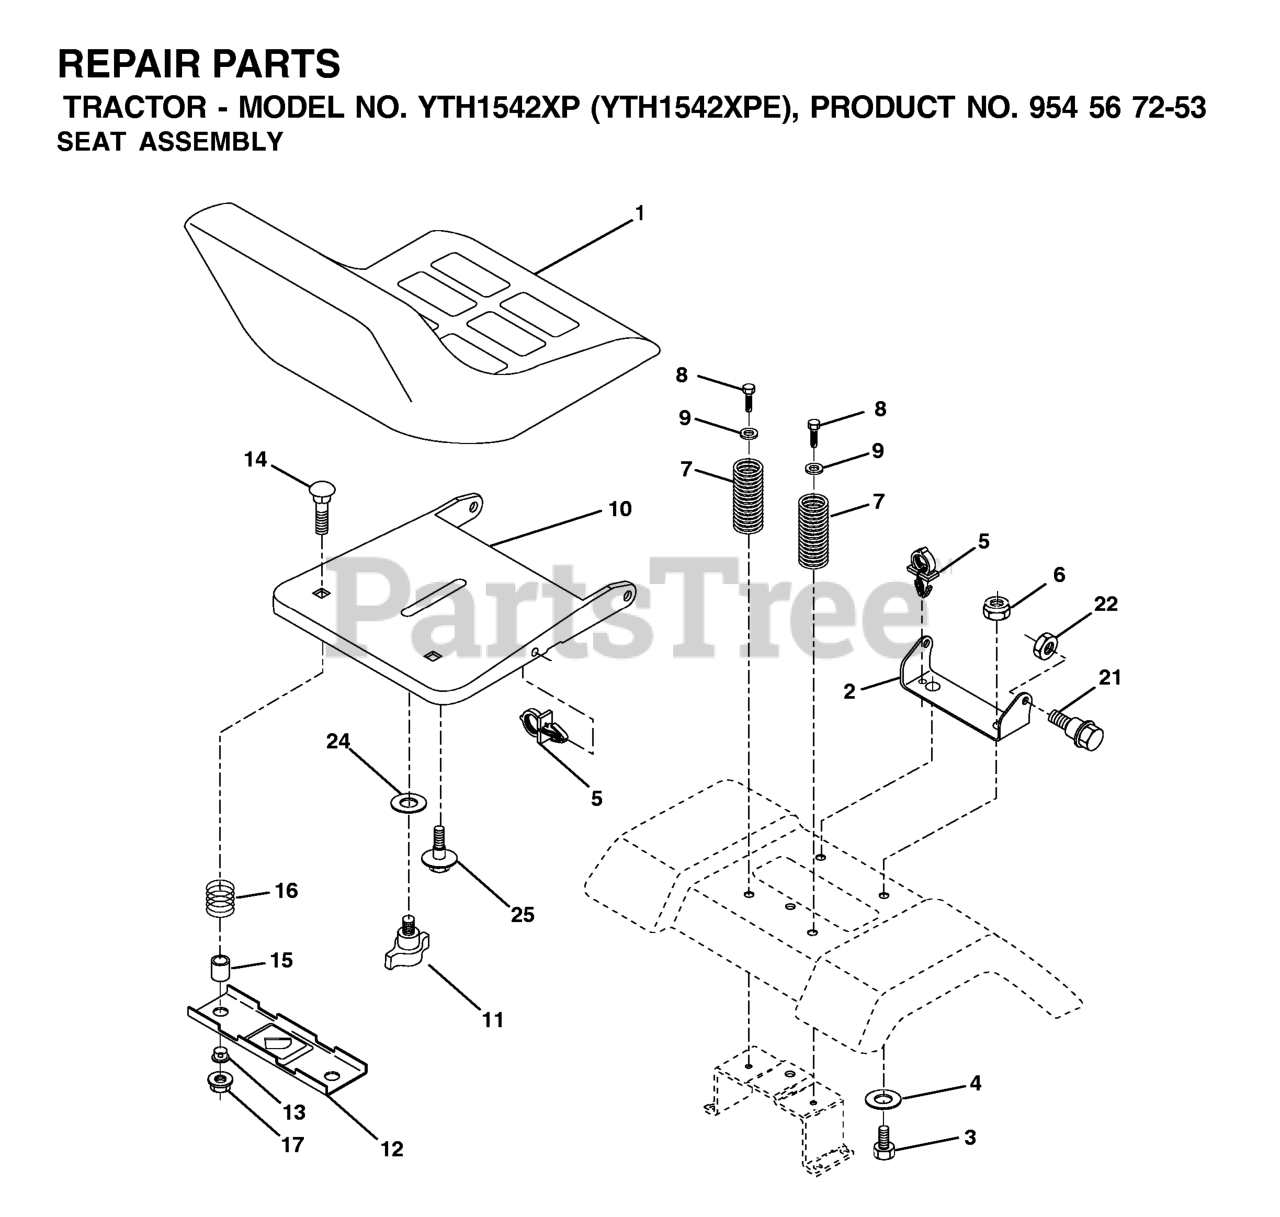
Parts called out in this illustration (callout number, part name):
1	SEAT, GRAY
2	SEAT PIVOT BRKT
3	BOLT, HEX 3/8-16X1
6	NUT
7	SPRING COMPRESSION
8	SCREW 3/8-16X1
9	WASHER
10	PAN, SEAT
11	KNOB.SEAT.ADJ.WINGNUT
12	BRKT SWITCH
14	BOLT.ROUND.HEAD.SQUARE.NECK
15	SPACER SPLIT
16	SPRING COMPRESSED
17	NUT T
21	BOLT.SHOULDER.5/16-18
22	NUT.71038.31-18.HEX.NYLOCK
25	BOLT,SHOULD
